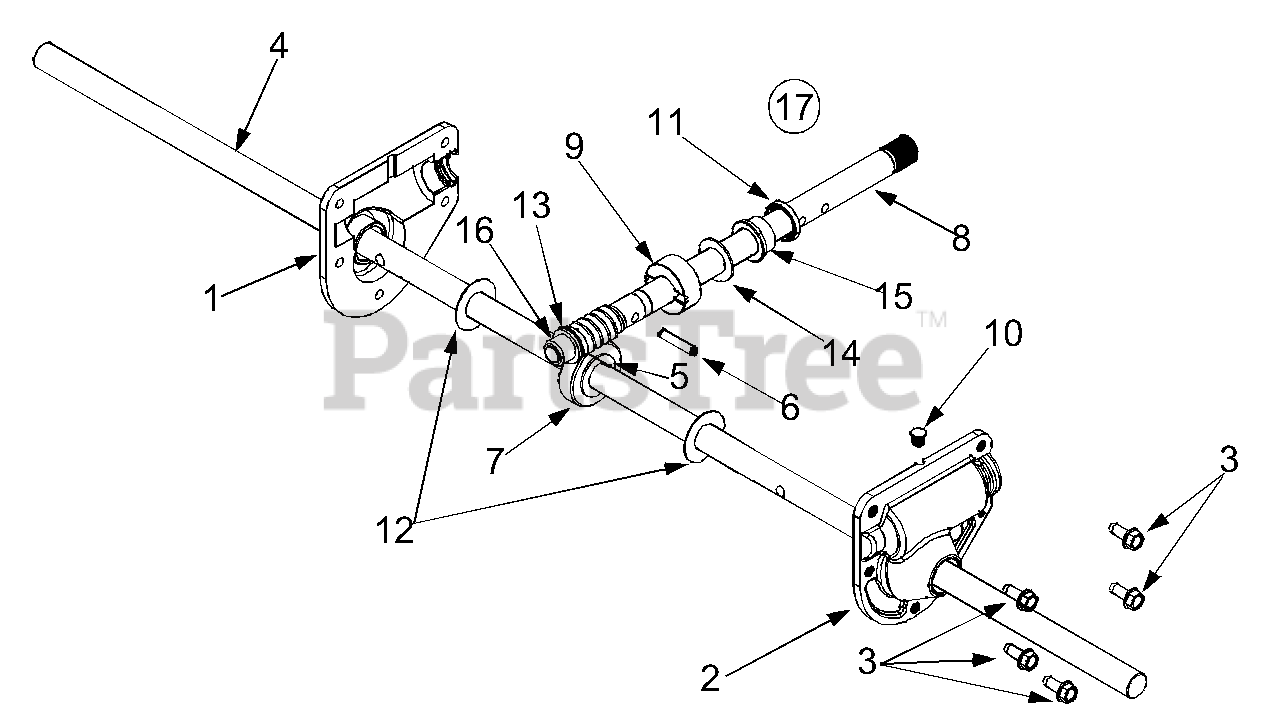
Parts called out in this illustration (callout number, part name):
1	Housing-R.H.
2	Housing-L.H.
3	Hex Screw 1/4-20 x .75
4	Spiral Axle 24"
4	Spiral Axle 26"
4	Spiral Axle 28"
4	Spiral Axle 30"
5	Key
6	Pin-Spiral
7	Gear-Worm
8	Shaft-Worm
9	Collar-Thrust
11	Seal-Oil
12	Washer-Flat
13	Washer-Flat
14	Washer-Flat
15	Bearing-Flange
16	Bearing-Flange
17	Ass'y. Complete 24"
17	Ass'y. Complete 26"
17	Ass'y. Complete 28"
17	Ass'y Complete 30"
